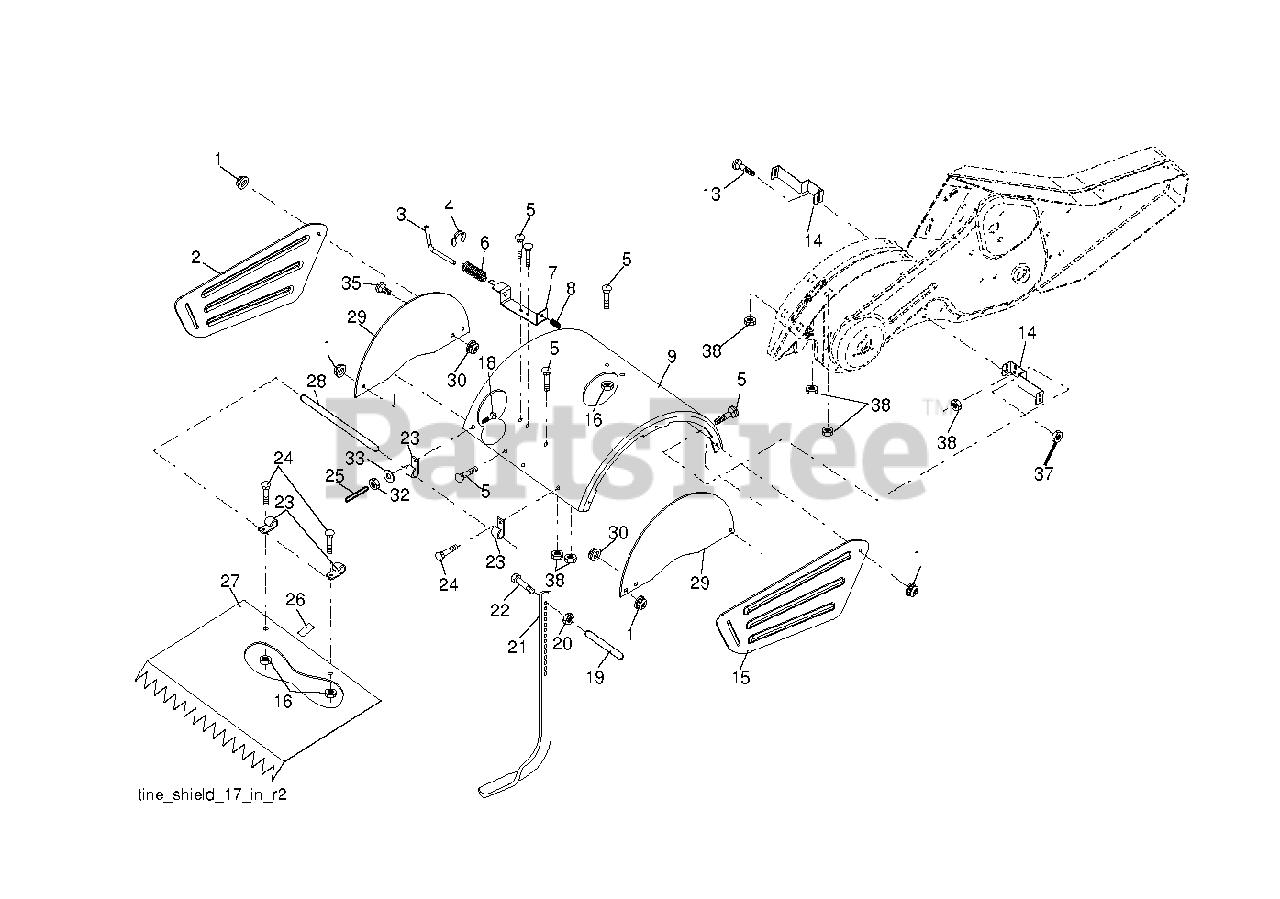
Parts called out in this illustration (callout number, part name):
1	NUT LOCK HEX FLANGE 5/16-18
2	SHIELD.SIDE.OUTER.LH.RED
5	BOLT, RDHD SQNK 5/16-18 X 3/4
7	LATCH BRACKET TI
9	SHIELD.TINE.RED
13	BOLT.CARRIAGE.5/16-18
14	BRACKET.TINE.SHIELD.TILLER
15	SHIELD.SIDE.OUTER.RH.RED
16	NUT T
20	NUT.HEX.3/8-16UNC
21	STAKE DEPTH CRT
24	BOLT
25	VINYL CAP TI
27	SHIELD.PNT.LEVELING.MS667
28	PIN.HINGE.TILLER
29	RP.SHIELD.ASM.PNT.SIDE.RED
30	LOCKNUT-FLANGE 5/16-18
32	NUT
33	LOCKWASHER
35	BOLT
37	NUT.71038.31-18.HEX.NYLOCK
38	NUT
